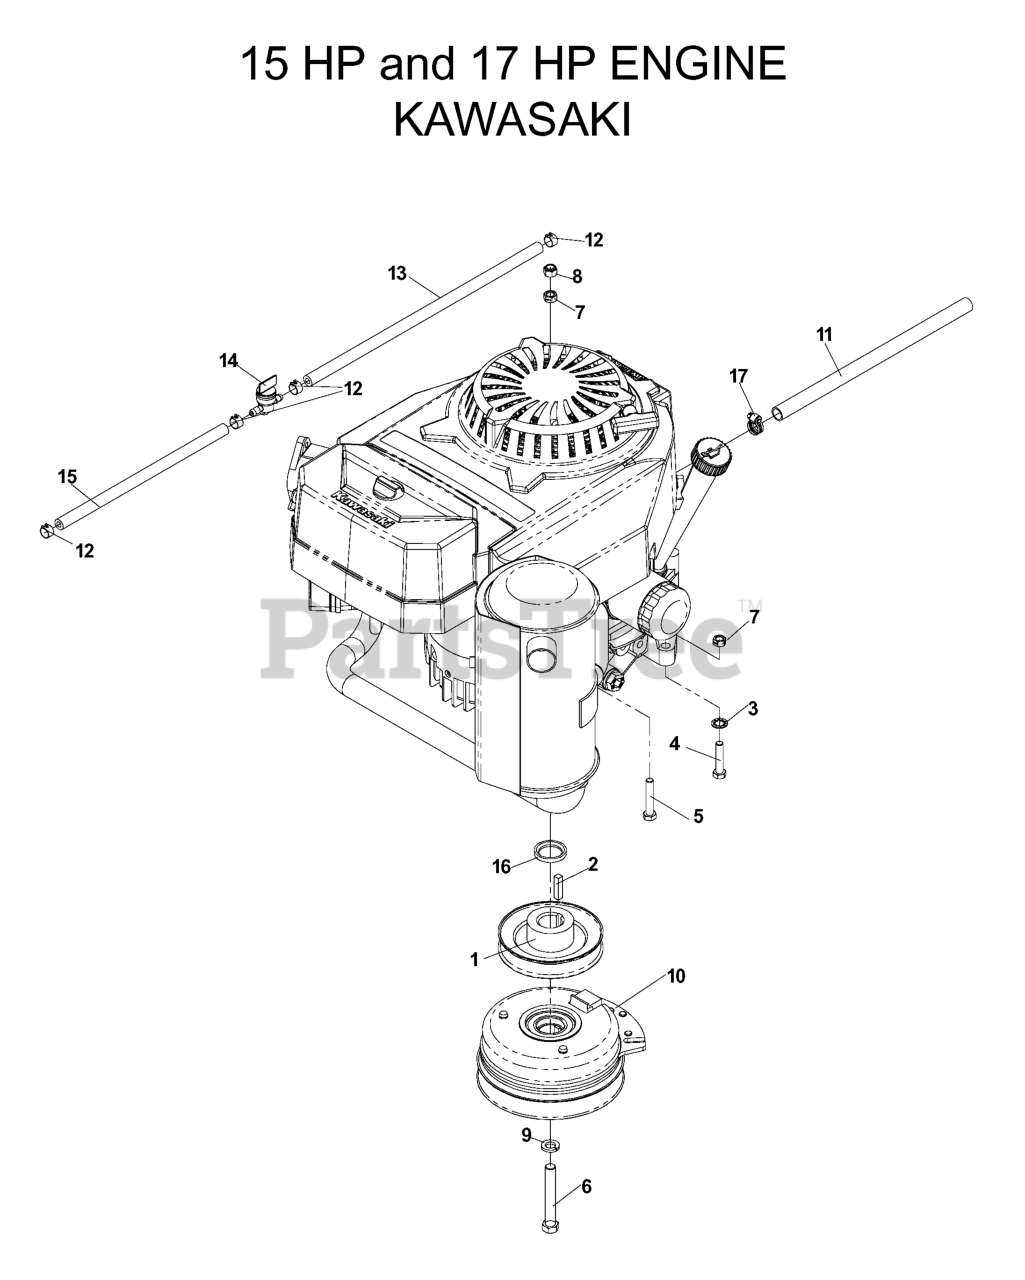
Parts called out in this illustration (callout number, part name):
2	KEY 1/4 SQ X 1 1/8
3	WASHER
4	CAPSCREW 5/16 X 1/1/2 HEX HEAD
5	HCS 5/16C X 1 3/4
6	HEX SCREW 7/16-20 X 3
7	NUT 5/16C CENTERLOCK
8	NUT 5/16 NYLOC
9	WASHER 7/16 LOCK
10	CLUTCH 125 FT/LB
11	OIL DRAIN HOSE
12	HOSE CLAMP
13	FUEL LINE 14"
14	FUEL VALVE
15	GAS LINE 10"
17	HOSE CLAMP T-1865
539105637	CLUTCH HARNESS
